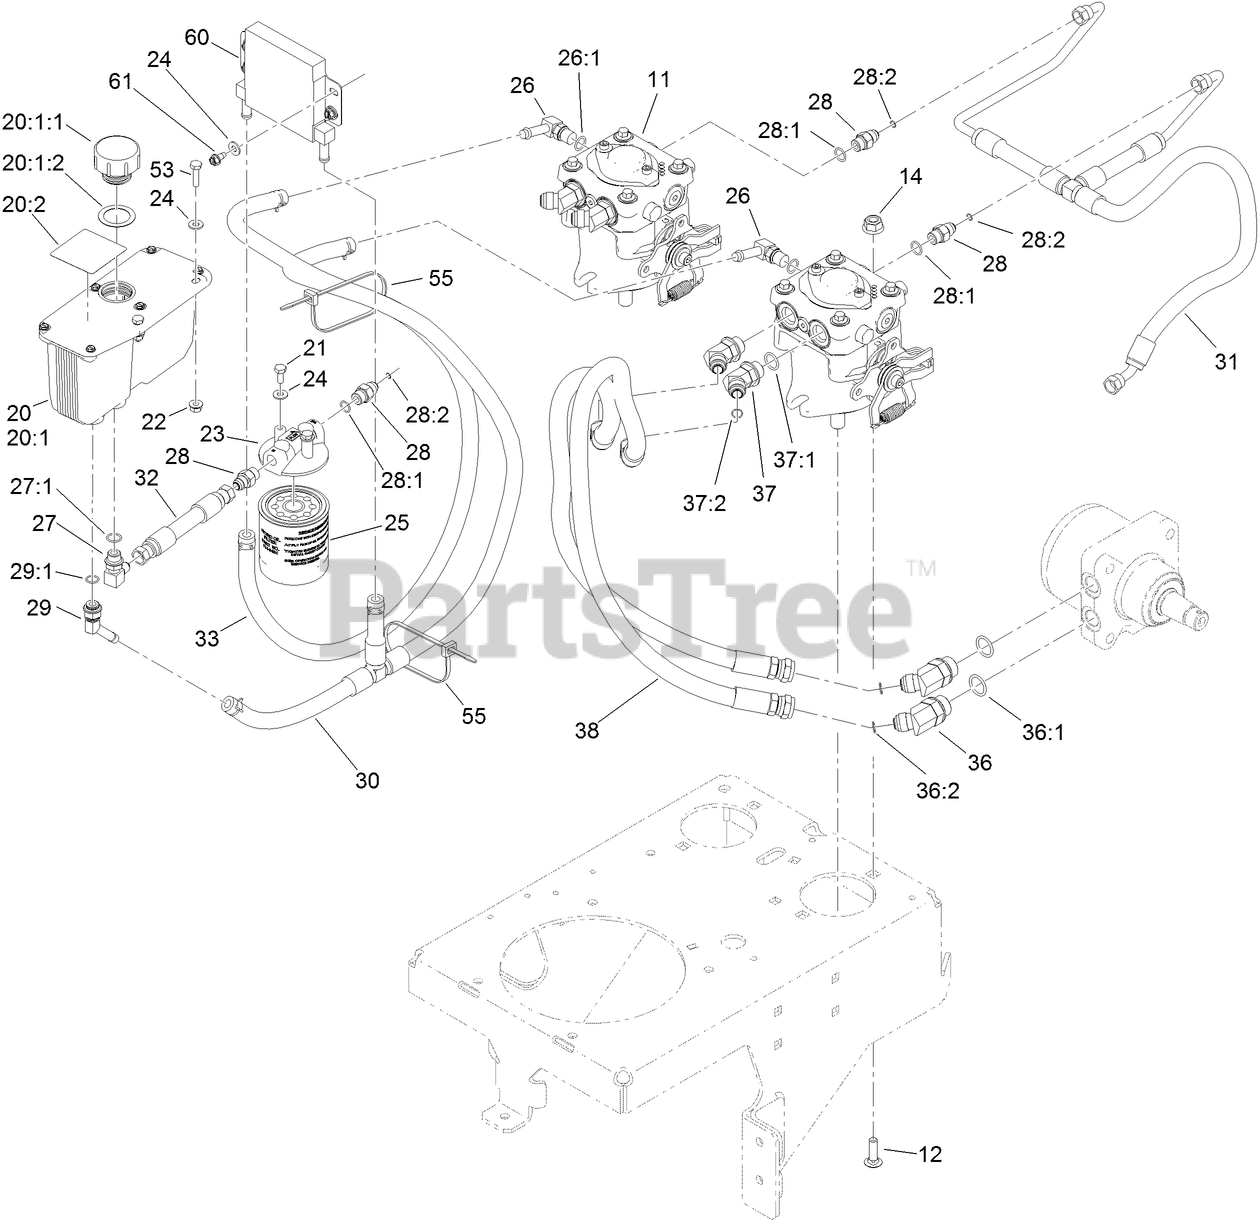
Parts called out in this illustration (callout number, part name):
11	HYDRAULIC PUMP ASM
12	BOLT-CARR
14	NUT-HF, NI
20	HYD RESERVOIR ASM
20:1	Reservoir-HYD
20:1:1	CAP-RESERVOIR, HYD
20:1:2	GASKET-CAP
20:2	DECAL-WARNING
21	SCREW-HH
22	NUT-HHF
23	HEAD-FILTER
24	WASHER-FLAT
25	ELEMENT-FILTER, 25 MICRON
26	FITTING-ELBOW, 90
26:1	O-RING
27	FITTING-ELBOW, 90 DEG
27:1	O-Ring
28	FITTING-STRAIGHT
28:1	O-Ring
28:2	O-RING
29	FITTING-BARBED, 45 DEG
29:1	O-RING
30	CASE DRAIN HOSE ASM
31	CHARGE HOSE ASM
32	HYD HOSE ASM
33	CASE DRAIN HOSE ASM
36	FITTING-HYD, 45 DEG
36:1	O-RING
36:2	O-Ring
37	FITTING-HYD, 45 DEG
37:1	O-RING
37:2	O-Ring
38	HYD HOSE ASM
53	SCREW-HH
55	TIE-CABLE
60	COOLER-OIL
61	SCREW-HWH
